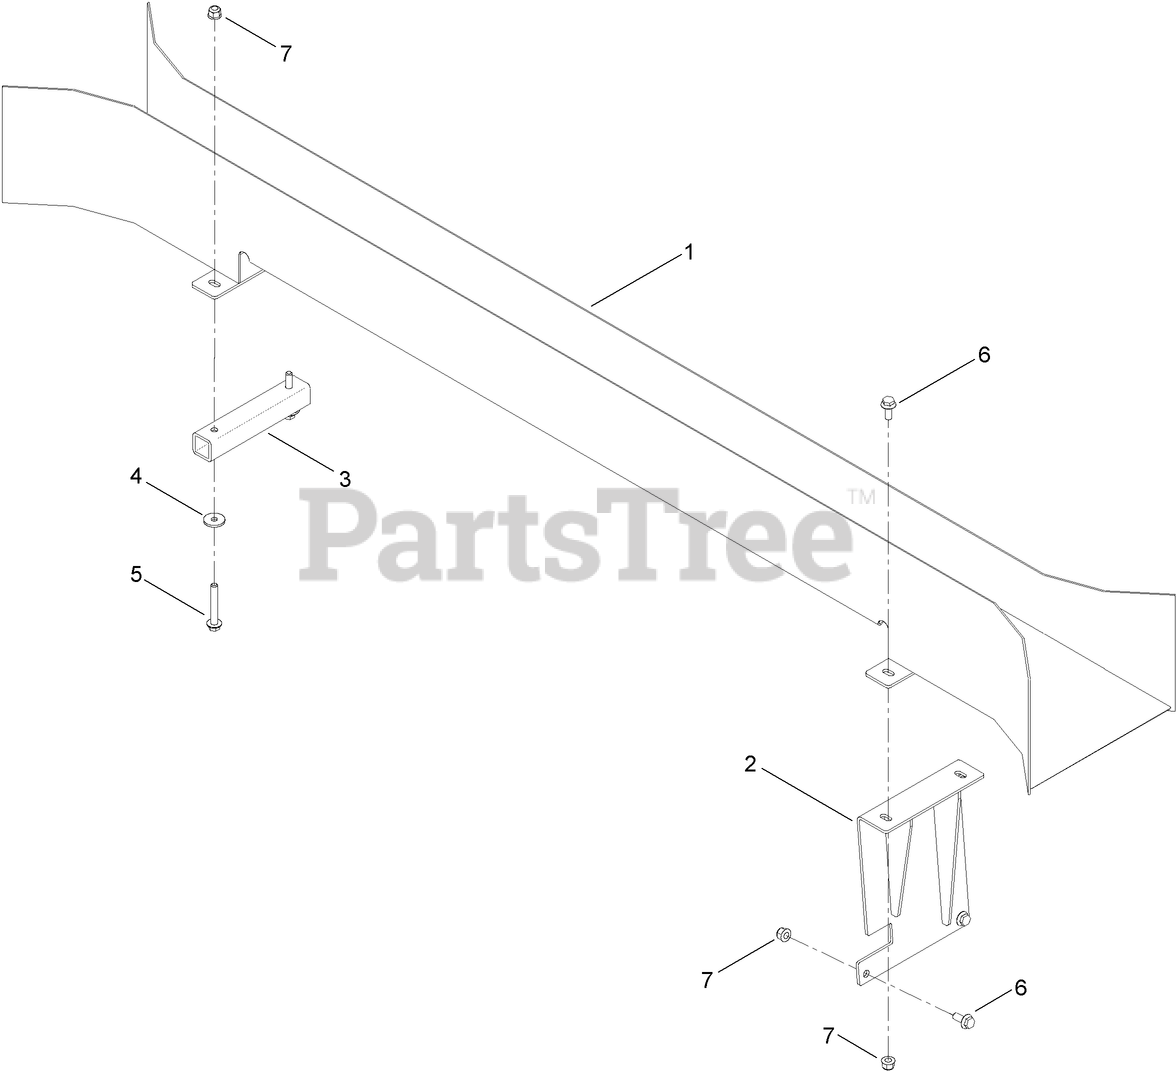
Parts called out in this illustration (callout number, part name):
1	CHUTE-CABLE
2	BRACKET-REAR, CABLE CHUTE
3	TUBE-SQUARE
4	SPACER-RUBBER
5	SCREW-HHF
6	SCREW-HHF
7	NUT-LOCK, NI
